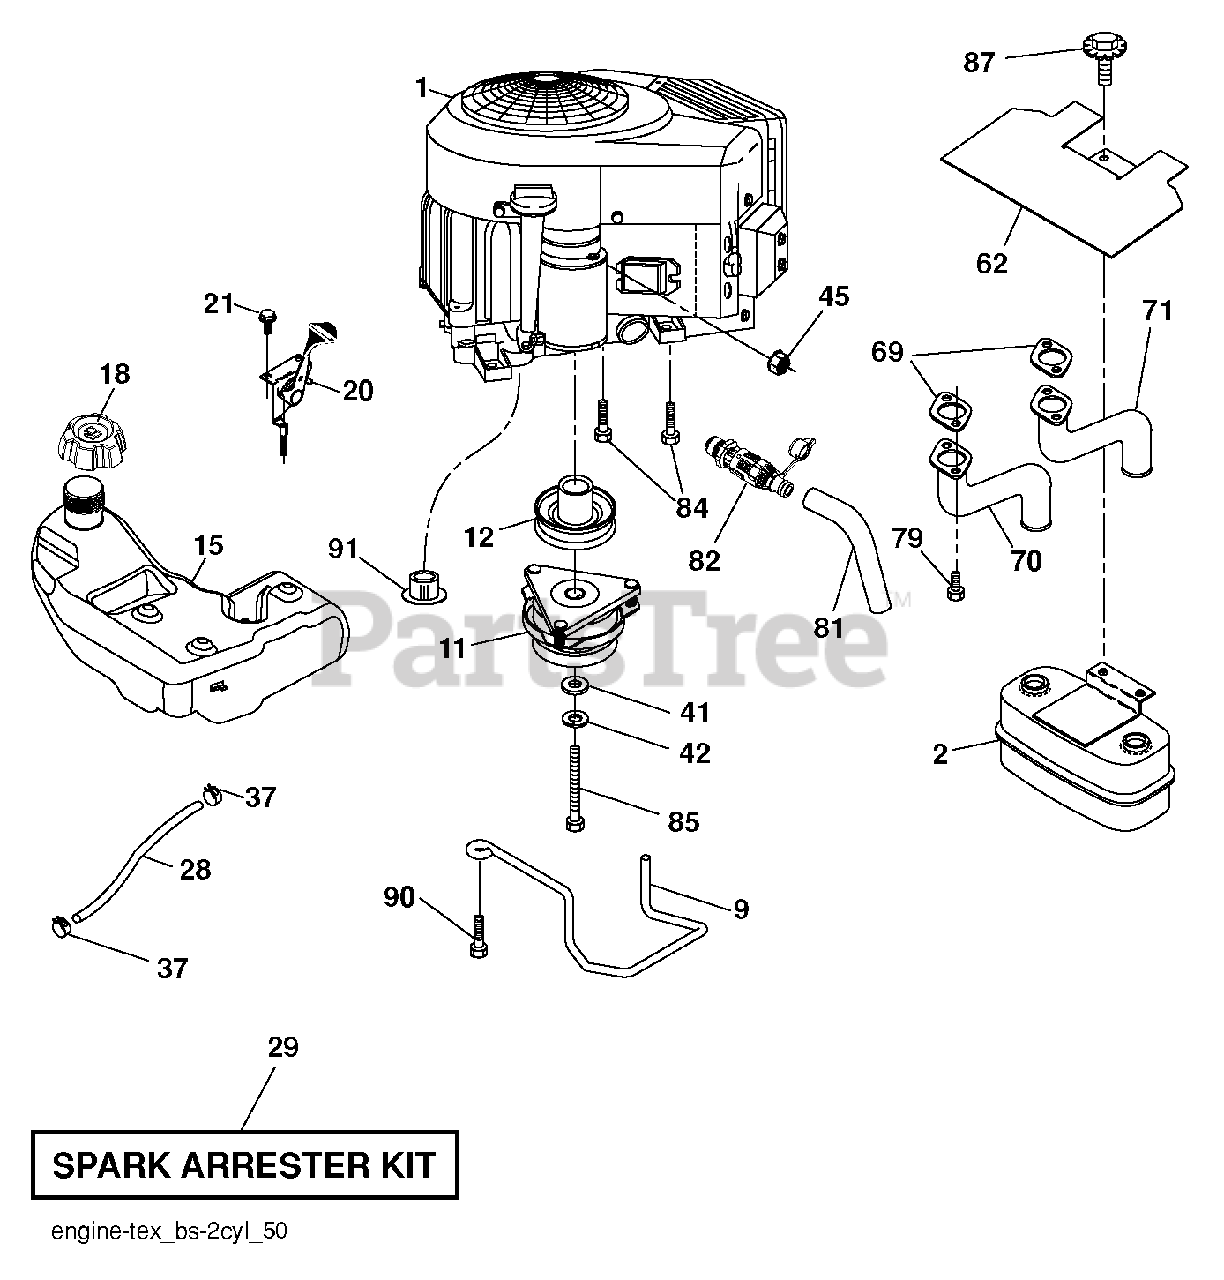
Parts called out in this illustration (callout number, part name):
1	Husqvarna TBD
2	MUFFLER.TWIN.CYL.LOW.TONE
9	KEEPER.BELT.ENGINE.4.2
11	CLUTCH.ELECTRIC.LT.48"*
12	PULLEY.ENGINE.TUFFTORQ
15	TANK.FUEL.SIDE-FILL.3.NON-EPA
18	RP CAP FUEL
20	CONTROL.TH/CK.COBRA.B&S.TWN.
21	SCREW.#10 X 0.750.BOS
28	LINE.FUEL.64"REAR.EMIS
29	SPARK ARRESTOR KIT
37	HOSE CLAMP
42	LOCKWASHER
45	NUT
62	MUFFLER.TWIN.CYL.LOW.TONE
69	GASKET.MUFFLER
70	RP.EXHAUST.TUBE.LH.BS/TWIN
71	EXHAUST.TUBE.RH.BS/TWIN
79	SCREW.SOCKET.HEAD.5/16-18
81	TUBE, DRAIN OIL ASM.
82	VALUE.OIL.DRAIN
84	SCREW.3/8-16
85	BOLT HEX 7/16-20X4-1/4"
87	BOLT, 5/16-18 X 1 3/4
90	SCREW 3/8-16X1
91	BUSHING.1.375OD
